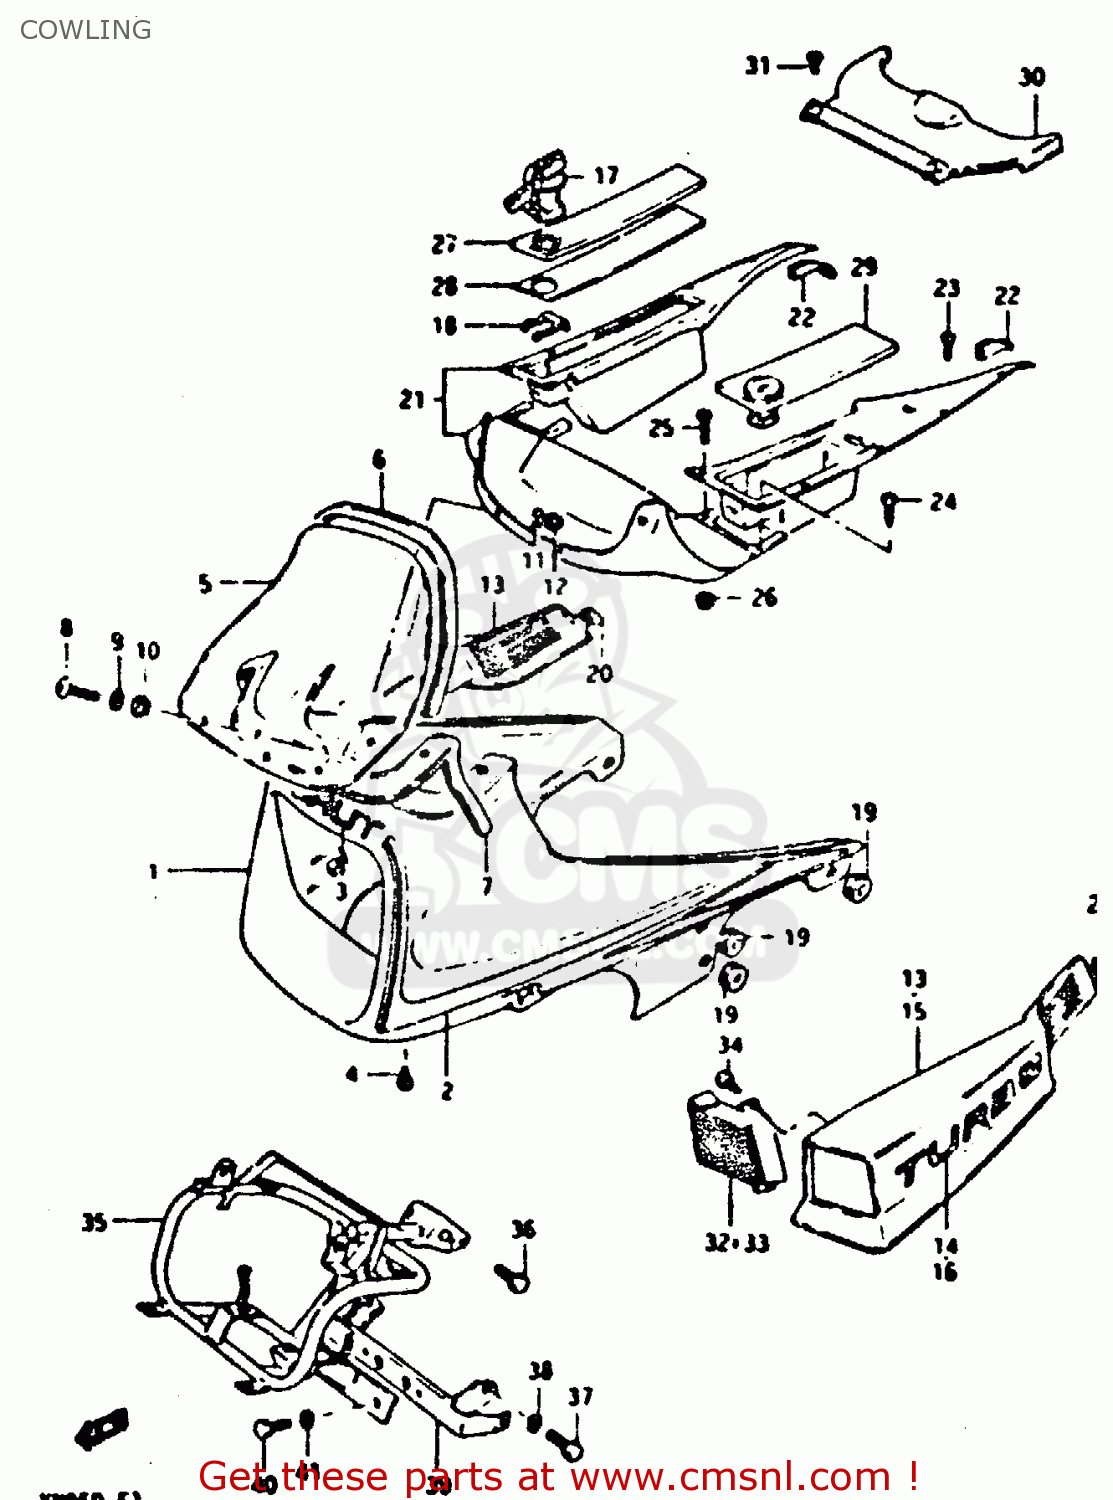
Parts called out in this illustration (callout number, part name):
1	COWLING ASSY
2	TAPE SET,COWLING
3	EMBLEM,COWLING,FRONT
4	SCREW 6X12
5	WINDOW
6	MOLDING
7	CUSHION,COWLING WINDOW
8	(5X20) CROSS SCREW
9	WASHER(5.2X11X1)
10	SPACER,COWLING WINDOW
11	WASHER
12	NUT
13	COVER,COWLING,RIGHT
14	EMBLEM,COVER SIDE
15	COVER,COWLING,LEFT
16	EMBLEM,COVER SIDE
17	LOCK,CONSOLE BOX
18	LOCK,HOLDER
19	CUSHION
20	CUSHION,COWLING COVER
21	PANEL,COWLING,UPPER
22	CUSHION
23	SCREW
24	SCREW
25	SCREW
26	NUT
27	COVER,FUSE BOX
28	CUSHION
29	COVER,FUSE BOX
30	INNER COVER,COWLING
31	SCREW
32	DUCT,COVER COWLING,RIGHT
33	DUCT,COVER COWLING,LEFT
34	SCREW
35	BRACE
36	BOLT
37	BOLT 8X12
38	LOCK WASHER
39	BRACE
40	BOLT
41	LOCK WASHER
